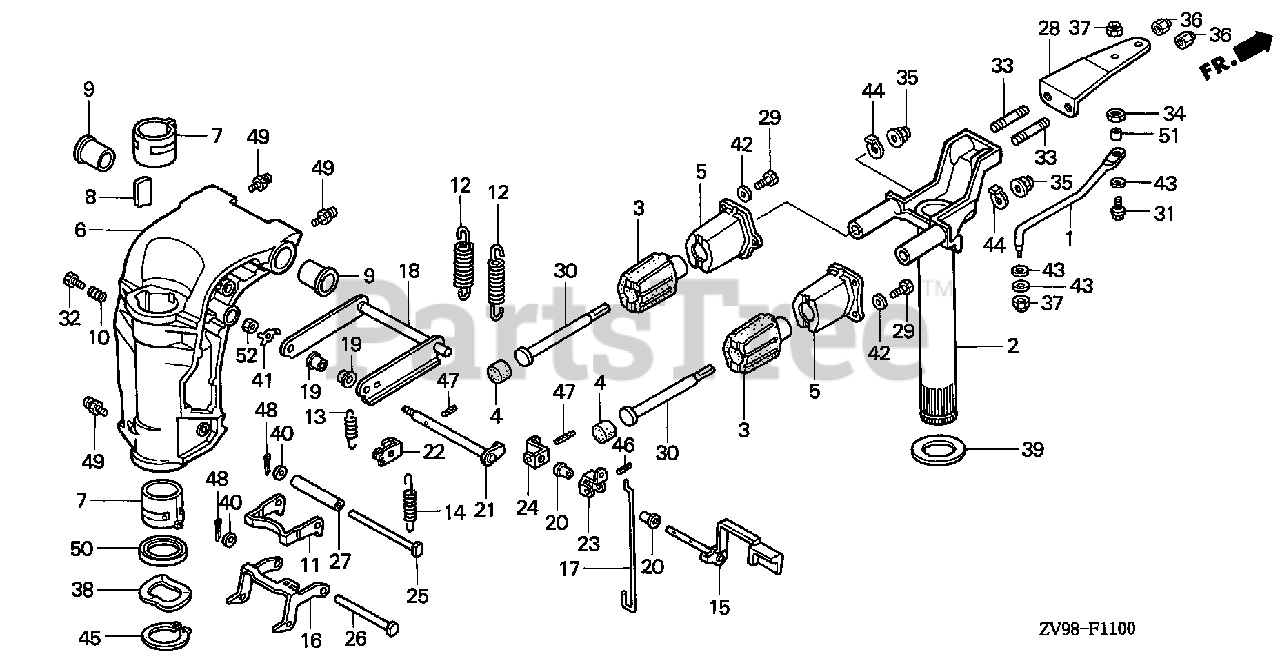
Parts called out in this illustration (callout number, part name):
1	ROD, STEERING
2	FRAME, MOUNTING *NH282MU* (OYSTER SILVER METALLIC-U)
3	RUBBER, MOUNTING (UPPER)
4	RUBBER, MOUNTING (UPPER) (B)
5	HOLDER, MOUNTING (UPPER) *NH282MU* (OYSTER SILVER METALLIC-U)
6	CASE, SWIVEL *NH282MU* (OYSTER SILVER METALLIC-U)
7	LINER, SWIVEL CASE
8	BLOCK, FRICTION
9	BUSH, SWIVEL CASE
10	SPRING, FRICTION ADJUSTING
11	HOOK, REVERSE LOCK
12	SPRING, REVERSE LOCK
13	SPRING, TILT LEVER
14	SPRING, TILT LINK
15	LEVER, TILT
16	ARM, REVERSE LOCK
17	ROD, RELEASE SWIVEL CASE
18	ARM, TILT
19	BUSH, TILT LEVER
20	BUSH, TILT LEVER
21	SHAFT, TILT
22	BRACKET, TILT SHAFT
23	BRACKET, RELEASE ROD
24	BRACKET, TILT LEVER
25	SHAFT, REVERSE LOCK (A)
26	SHAFT, REVERSE LOCK (B)
27	COLLAR, REVERSE LOCK
28	PLATE, STEERING
29	BOLT, HEX. (6X18)
30	BOLT, SPECIAL (10X130)
31	BOLT (3/8-24 UNF)
32	BOLT, SPECIAL (8X20)
33	BOLT, STUD (10X28)
34	NUT (3/8-24 UNF)
35	NUT, FLANGE (10MM)
36	NUT, SELF-LOCK (10MM)
37	NUT, SELF-LOCK (3/8-24UNF)
38	WASHER, WAVE (40MM)
39	WASHER, THRUST (34MM)
40	WASHER, PLAIN (6MM)
41	WASHER, LOCK
42	WASHER, PLAIN (6MM)
43	WASHER (10MM)
44	WASHER, SPECIAL
45	CIRCLIP (OUTER) (39MM)
46	PIN, SPRING (3.0X22)
47	PIN, SPRING (3.0X25)
48	PIN, SPLIT (2.0)
49	NIPPLE, GREASE
50	OIL SEAL (39.5X52X6) (ARAI)
51	COLLAR, STEERING ROD
52	NUT, HEX. (6MM)
